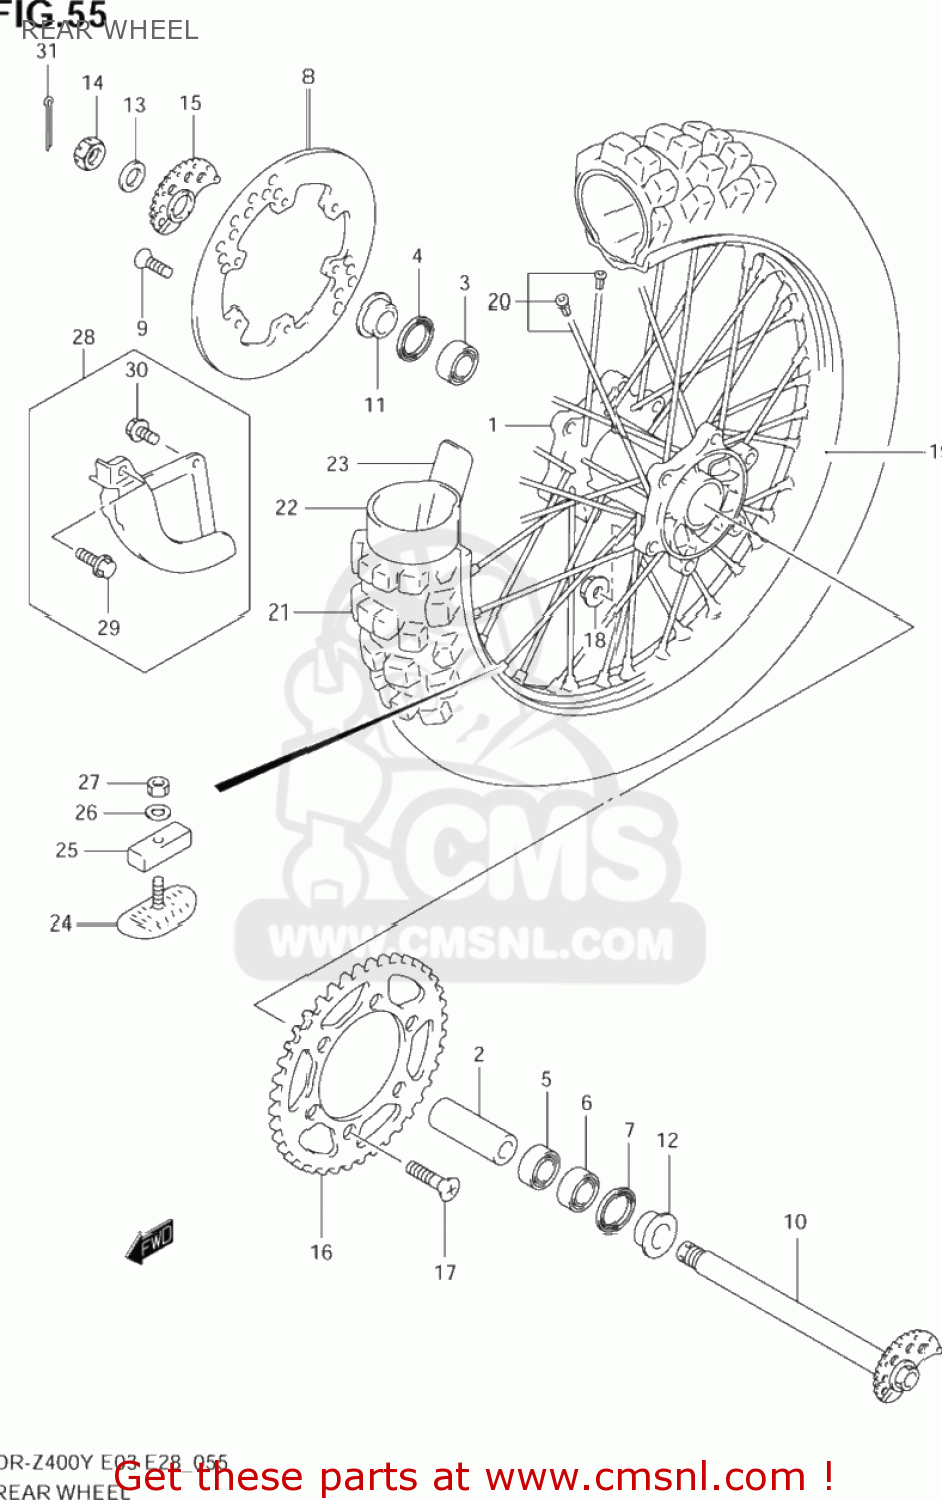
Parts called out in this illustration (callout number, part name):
1	HUB,RR WHEEL
2	SPACER,RR HUB BEARING
3	BEARING
4	SEAL(29X42X6)
5	BEARING
6	BEARING
7	SEAL,OIL(29X47X6)
8	DISC,RR BRAKE
9	SCREW
10	AXLE,RR
11	SPACER,RR AXLE
12	SPACER,RR AXLE
13	WASHER(19X32X3.2)
14	NUT
15	ADJUSTER,CHAIN,R
16	SPROCKET,RR(NT:47-520)
17	BOLT(8X30.5)
18	NUT
19	RIM,RR WHEEL(18X2.15 AL)
20	SPOKE SET,RR WHEEL
21	TIRE,RR(110/100 18 64M)
22	TUBE ASSY,WHEEL INNER
23	PROTECTOR,WHL INR TUBE
24	STOPPER,BEAD(2.15)
25	CUSHION,BEAD STOPPER
26	WASHER
27	NUT
28	COVER SET,RR BRAKE DISC
29	BOLT
30	BOLT
31	PIN,COTTER
